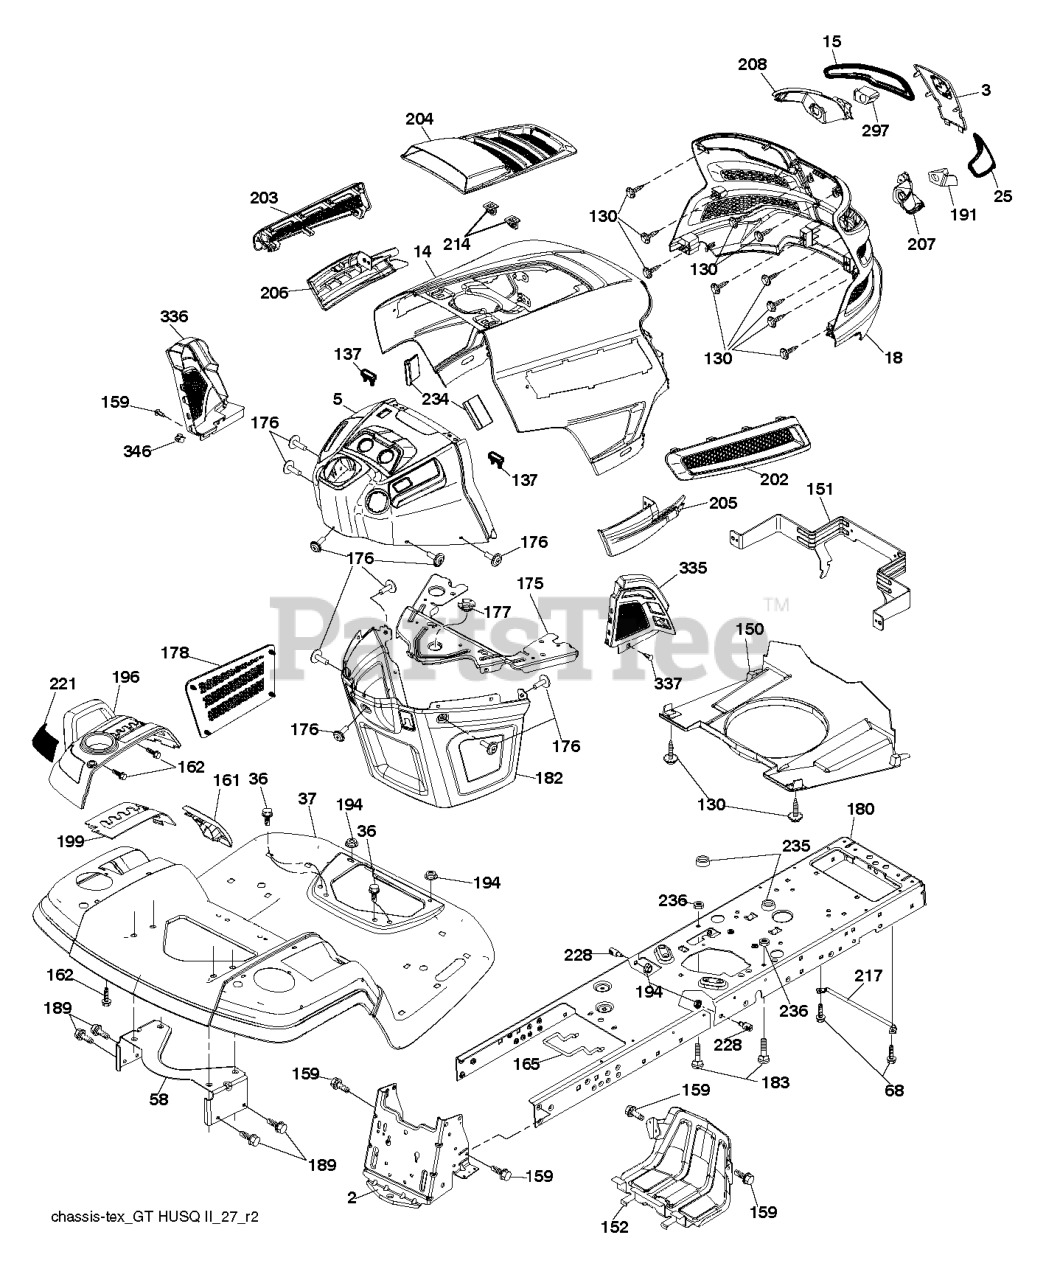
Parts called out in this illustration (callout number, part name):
2	DRAWBAR.STGT
3	APPLIQUE.SUBASM.GT.HUSQ.II
5	DASH.UPP.GT2.DUAL.RD.PTO.MCHOK
14	HOOD.ASM.HUSQVARNA.GT.TEX.ORAN
15	LENS.HEADLIGHT.LH.GTII.2011
18	GRILLE.SUBASM.GT.HUSQ.II
25	LENS.HEADLIGHT.RH.GTII.2011
36	SCREW 5/16"
37	FENDER.PNT.TX.GT.CH/FW/DL.HUSQ
58	BRKT.SUPPORT.FNDR/TANK
68	SCREW LT
130	SCREW.#10 X 0.750.BOS
137	BUMPER DASH
150	AIR.DUCT.GTV.BLACK
151	BRACKET.PIVOT.HOOD.GT.HUSQ.II
152	SHIELD.BROWNING.PNT.GT.V2
159	SCREW, 3/8-16X3/4
161	CONSOLE.WINDOW.FUEL.HUSQ.GT
162	SCREW.HI-LO.CONSOLE
165	SUPPORT.TANK.REAR.B/TE
175	PLATE.CROSSMEMBER.HUSQ
176	SCREW.#10-24X5/8.RN.QU
177	BUSHING, STEERING
178	CARGO.ASM.NET.TXGT.W/C
180	CHASSIS.STAMPING.LT/GT
182	DASH.LOWER.COMMON.12V.ADAPTOR
183	BOLT.5/16-18X1-1/4 FULL THD
189	SCREW
191	INSERT.REFLECTIVE.RH.HUSQ.GTII
194	NUT LOCK HEX FLANGE 5/16-18
196	CONSOLE.ASM.DECKLIFT.HUSQGT.DL
199	PLATE.DECK.LIFT.HUSQVARNA.GT
202	VENT.SIDE.RH.GT.HUSQ.II.
203	VENT.SIDE.LH.GT.HUSQ.II.498
204	VENT.TOP.HUSQ.GT2
205	SIDE.TRIM.RH.GT.HUSQ.II
206	SIDE.TRIM.LH.GT.HUSQ.II.GRAY
207	BEZEL LIGHT.RH.GT.II.MYLAR
208	BEZEL LIGHT.LH.GT.II.MYLAR
214	CLIP.RETAINER.TINNER.
217	ROD.PIVOT.HOOD
221	REFLECTOR.LH.TEX GT HU
228	STUD.FASTNER.W/ANTI-ROTATE
234	BUMPER.HOOD.TEX.HUSQVARNA
235	SPACER FENDER
236	NUT.CENTERLOCK.5/16-
297	INSERT.REFLECTIVE.LH.HUSQ.GTII
335	COVER.RH.CLOSE.OUT.BLACK
336	COVER-LH.LOWER.DASH.GT2.BLACK
337	CLIP.XMAS.TREE.ITW.2622-00
346	CLIP,INSULATOR
